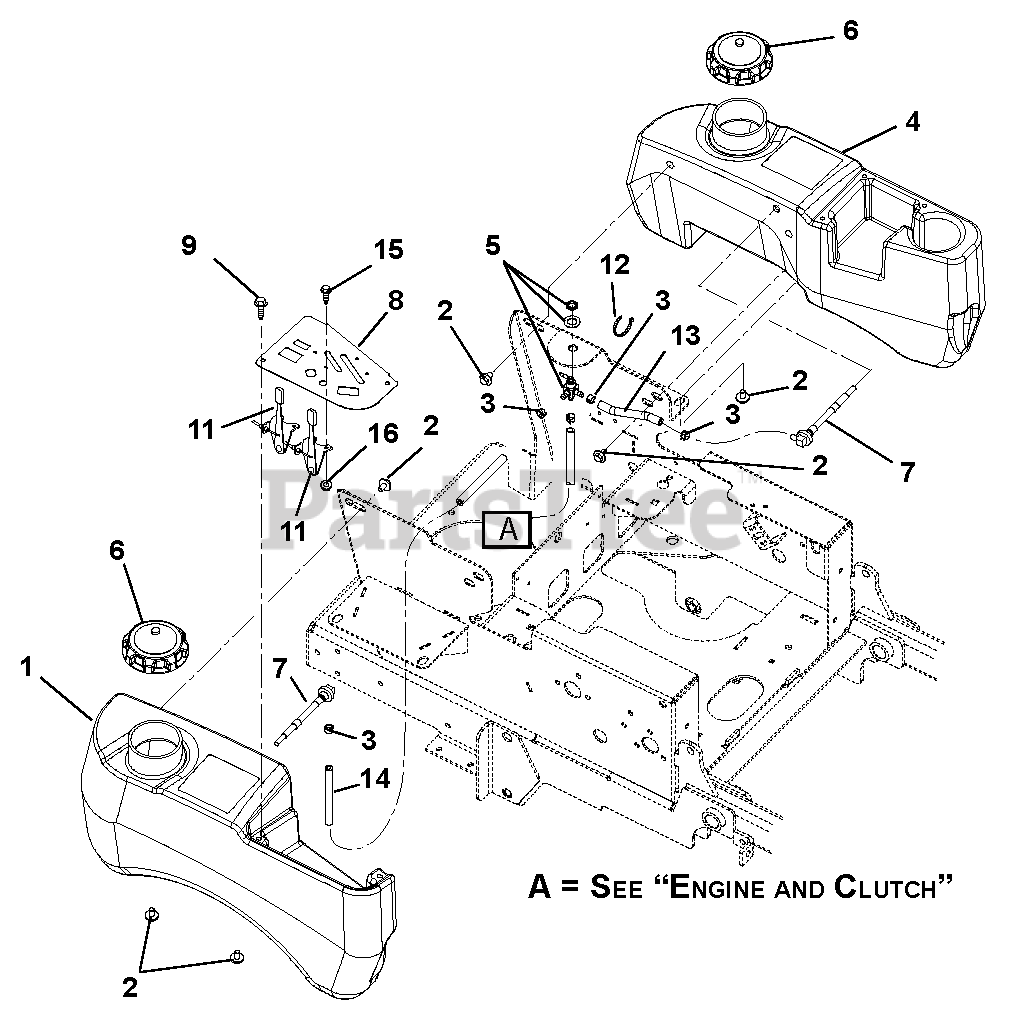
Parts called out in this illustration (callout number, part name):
1	Tank, Fuel RH (S/N 101 – 2499)
1	Tank, Fuel RH (S/N 2500 and up)
2	Bolt, SEMS .31-18 x .62
3	Clamp, Fuel Line
4	Tank, Fuel LH (S/N 101 – 2499)
4	Tank, Fuel LH (S/N 2500 and up)
5	Valve, Fuel
6	Cap, Fuel (S/N 101 – 2499)
6	Cap, Fuel Ratcheting (S/N 2500 and up)
7	Assembly, Tank Fuel Pick-up
8	Panel, Control
9	Screw, Machine 10-24 x .50 Stainless
10	Cable, Throttle
11	Cable, Control
12	Cable Tie
13	Hose, .25 Low-PERM Bulk Gas
14	Hose, .25 Low-PERM Bulk Gas
15	Screw, Machine 10-24 x .50 Hex Washer Head
16	Nut, Locking-Nylon 10-24 with Insert
